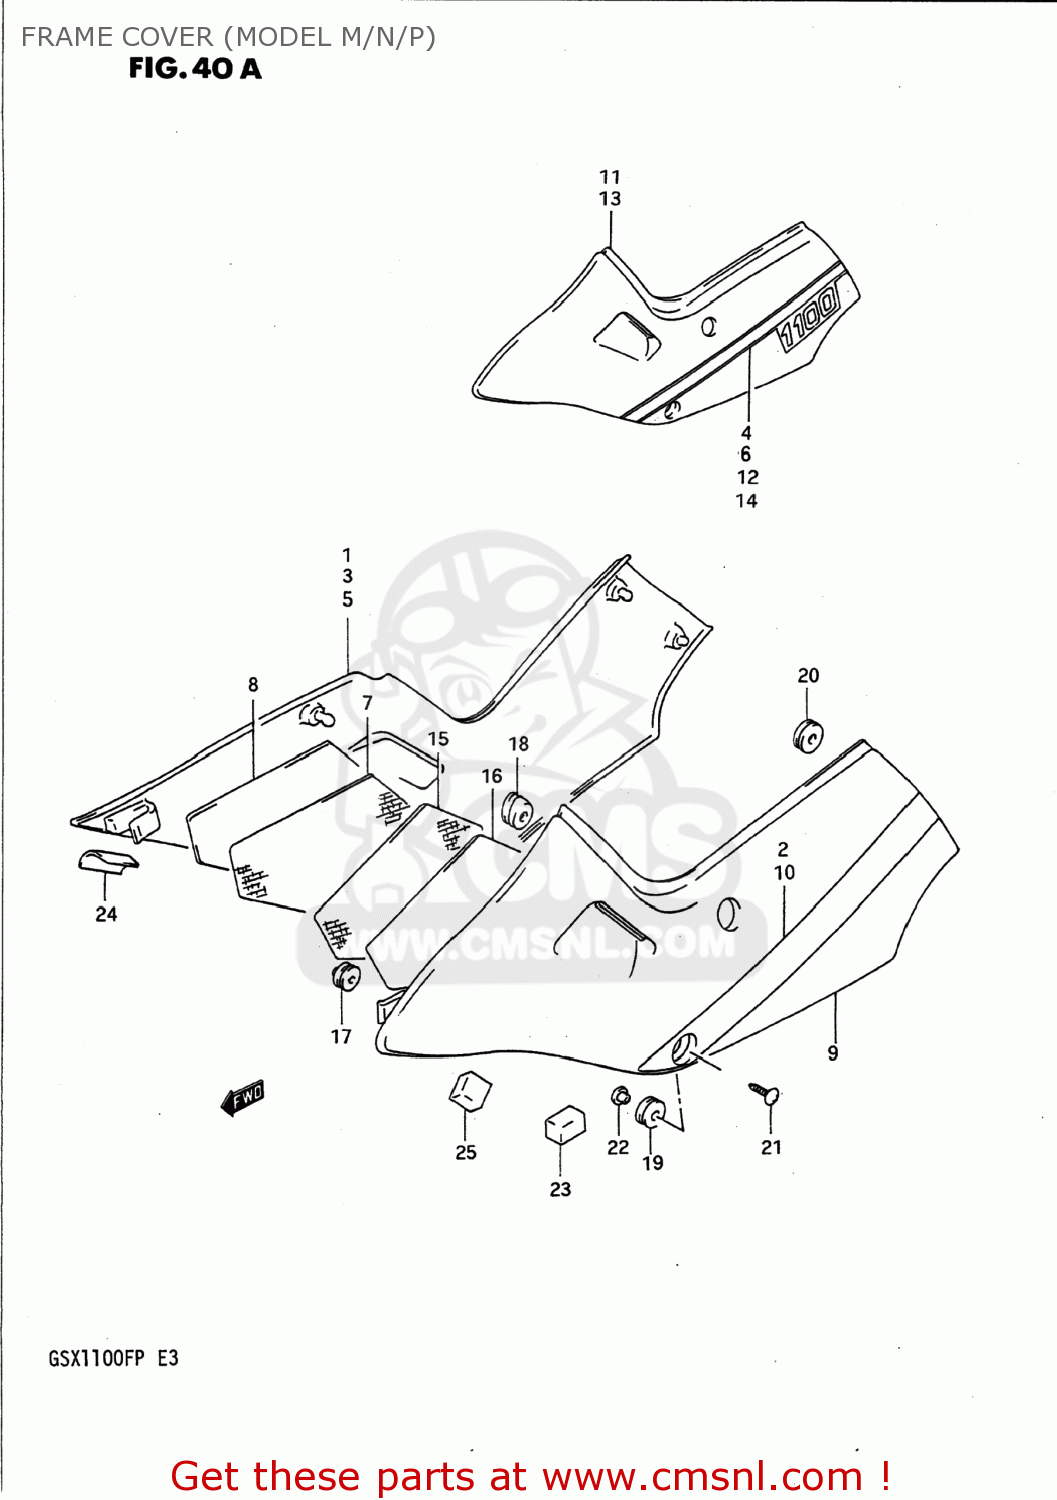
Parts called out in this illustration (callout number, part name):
1	COVER COMP,FRAME,RIGHT
2	TAPE,FRAME COVER STRIPE
3	COVER COMP,FRAME,RIGHT
4	TAPE,FRAME COVER,RIGHT
5	COVER COMP,FRAME,RIGHT
6	EMBLEM,FRAME COVER,RIGHT
7	HEAT SHIELD,FRAME COVER
8	BALANCER,SEAT FRAME COVER
9	COVER,FRAME,LEFT
10	TAPE,FRAME COVER STRIPE
11	COVER COMP,FRAME,LEFT
12	TAPE,FRAME COVER,LEFT
13	COVER COMP,FRAME,LEFT
14	EMBLEM,FRAME COVER,LEFT
15	HEAT SHIELD,FRAME COVER
16	BALANCER SHEET,FRAME C
17	CUSHION,COVER FRAME FR NO.1
18	CUSHION,COVER FRAME FR NO.2
19	CUSHION,SEAT TAIL COVER SIDE
20	CUSHION
21	SCREW
22	WASHER
23	CUSHION,FRAME COVER
24	CUSHION
25	PROTECTOR,FRAME COVER FR
